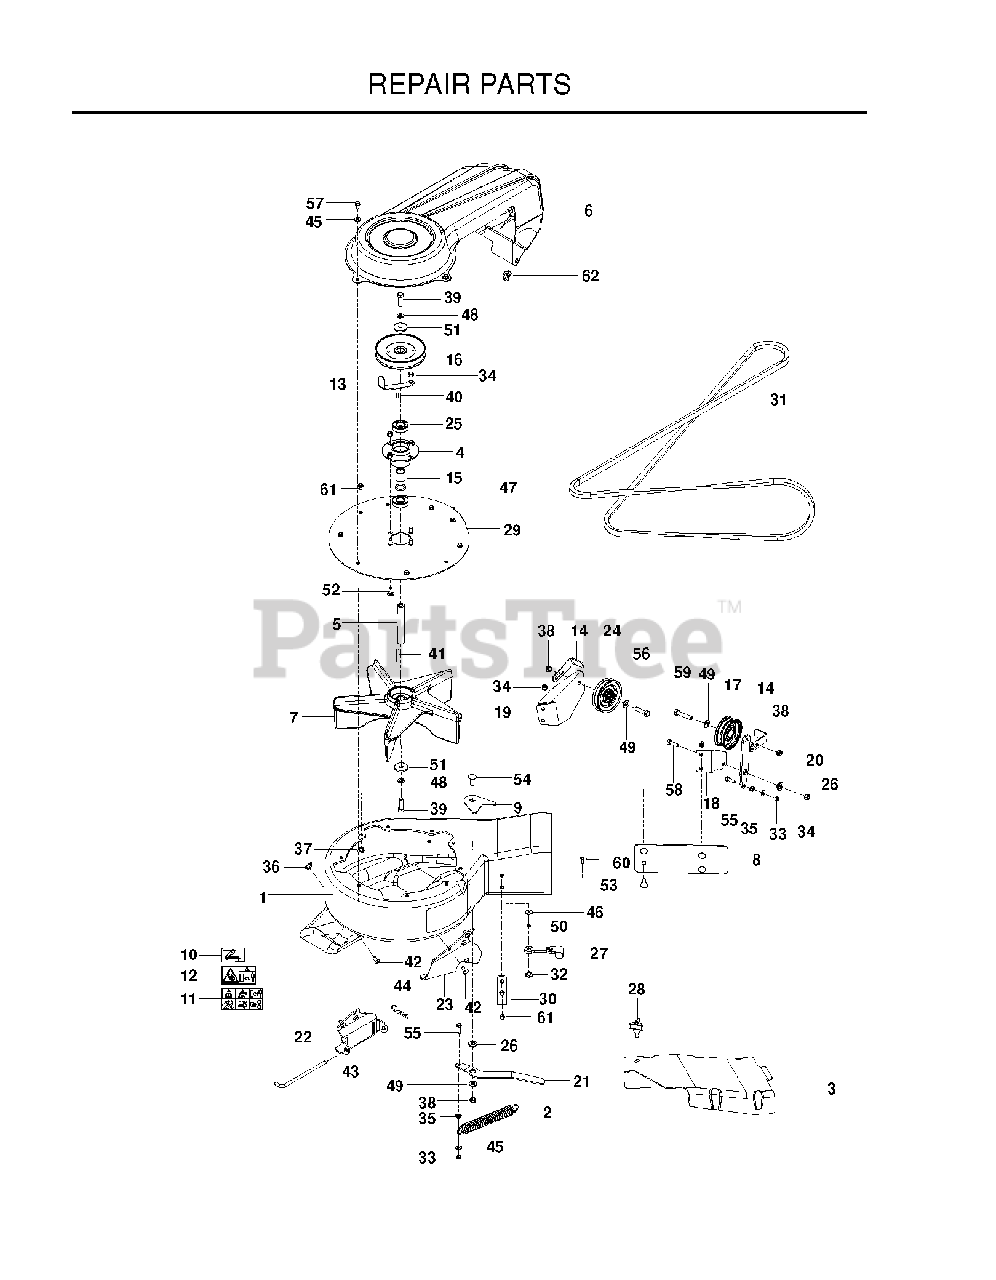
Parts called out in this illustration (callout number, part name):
1	BLOWER.HOUSING.W/DECALS.COLLEC
3	COVER, BELT
4	HUB, BEARING
5	SHAFT, IMPELLER
6	COVER, BELT
7	IMPELLER.COLLECTION.BLOWER.BLA
8	PLATE.BACKING.BLACK
9	PLATE, BACKING
10	DECAL, BELT ROUTING
11	DECAL, EURO WARNING
12	EURO DECAL, IMPELLER
13	KEEPER, BELT, OUTER
14	KEEPER, BELT, REAR
17	IDLER PULLEY
18	MOUNT, IDLER, UPPER
19	MOUNT, IDLER, LOWER
20	ARM, IDLER
21	ARM, TENSION
22	BRKT, MT, FRONT
23	BRKT, MT, REAR
24	V-IDLER
25	BEARING
26	BUSHING
27	HOOD LATCH
28	KNOB W/STUD
29	PLATE, OUTER
31	Belt for 48" and 52" Grass Collection System
32	NUT 10-24 WELD PLATED
33	JAM NUT 1/4C
34	NUT 5/16 NYLOC
35	NUT 1/4-20 HEX FLG LK ZD
36	NUT 5/16-18 TEE
37	NUT 1/4-20 TEE
38	NUT HEX 3/8-16 NYLON, THIN
39	BOLT, HEX 3/8-24 X 1.25 GR 8
40	KEY, 3/16 X 1/2
41	KEY-SQ. 3/16 X 1 1/2
42	HCS 5/16-18 X 1/2 GR 5 ZD
44	HAIRPIN #2
45	WASHER 1/4 SAE
47	WASHER .787 X 1.125 X .06
48	SLW 3/8 STD
49	WASHER 3/8 SAE FLAT
50	WASHER - 3/16 LOCK ZD
51	WASHER, HARDENED
52	BOLT 5/16C X 3/4" CARRIAGE
53	RHSNB 5/16C X 1
54	RHSNB 3/8C X 1
55	HCS 1/4-20X7/8 GR5
56	HCS 3/8C X 1 1/2
57	BOLT 1/4-20 X 1/2 HWST
58	HCS 5/16C X 1
59	BOLT, HCS 3/8-16X1-3/4
60	SCREW #10-24 X 5/8
61	HWST 1/4C X 3/8
62	U-CLIP 5/16-18 NUT RETAINER
